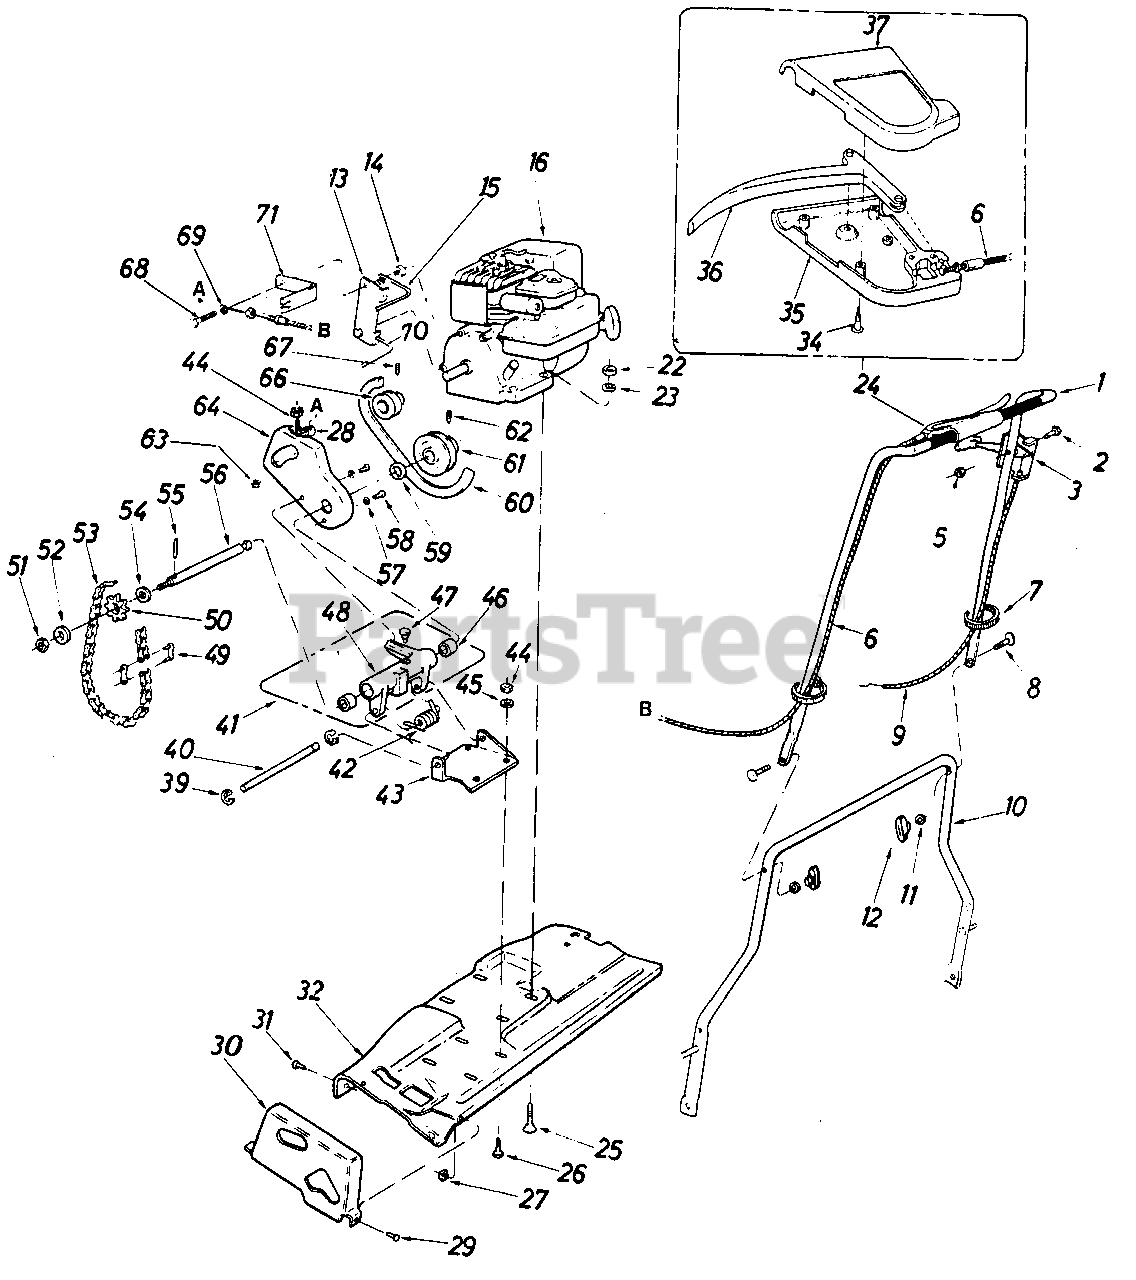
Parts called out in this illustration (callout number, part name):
1	Upper Handle Ass'y.
2	Rd. Hd. Scr.1/4-20 x 1.88" Lg.
3	Throttle Control Ass'y.
5	Capped Wash. Z-Nut
6	Clutch Control Cable
7	Cable Tie
8	Special Scr. 5/16-18 x 1.75" Lg.
9	Throttle Cable
10	Lower Handle Ass'y.
11	L-Wash. 5/16
12	Handle Knob
13	Belt Keeper Brkt
14	Spacer
15	Belt Keeper Upper
22	Hex Nut 516-18 Thd.
23	L-Wash. 5/16
24	Clutch Control Ass'y.
25	Carriage Bolt 5/16-18 x 1.375" Lg.
26	Scr. 1/4-20 x .625" Lg.
27	Hex L-Nut 10-32 Thd.
28	Clevis Lanyard Fitting
29	Ph. Hd. Scr. 10-32 x .375" Lg.
30	497 Chain Guard
31	Hex Sems Scr. 5/16-24 x .50 Lg.
32	18" Deck
34	Slotted Oval Self-Tap Scr. #10 x .87" Lg.
35	Rear Control Cover
36	Lever Clutch Control
37	Front Cover Control
39	Retaining Ring
41	Jack Shaft Hsg. and Brg. Ass'y.
42	Spring
43	Bracket
44	Hex Nut 1/4-20 Thd.
45	1/4 Split L-Wash.
46	Bearing
47	Oiler
48	Jack Shaft Hsg.
49	Connector Link
50	Sprocket
51	Hex Jam Nut 5/16-24
52	Washer
53	Chain
54	Wash. 5/8 x 15/16
56	Jack Shaft
57	Washer
58	Ph. Hd. Scr. 10-32 x .50" Lg.
59	Wash. 5/8 x 15/16
60	"V" Belt
61	Pulley Ass y.
62	Roll Pin
63	Hex Nut 1/4-20 Thd.
64	497 Belt Guard Ass'y.
66	Pulley
67	Set Scr. 5/16-24 x 7/32" Lg.
68	Ph. Hd. Scr. 1/4-20 x 1.75" Lg.
69	L-Wash. 1/4" Scr.
70	Belt Keeper Lower
71	Clutch Cable Bracket
